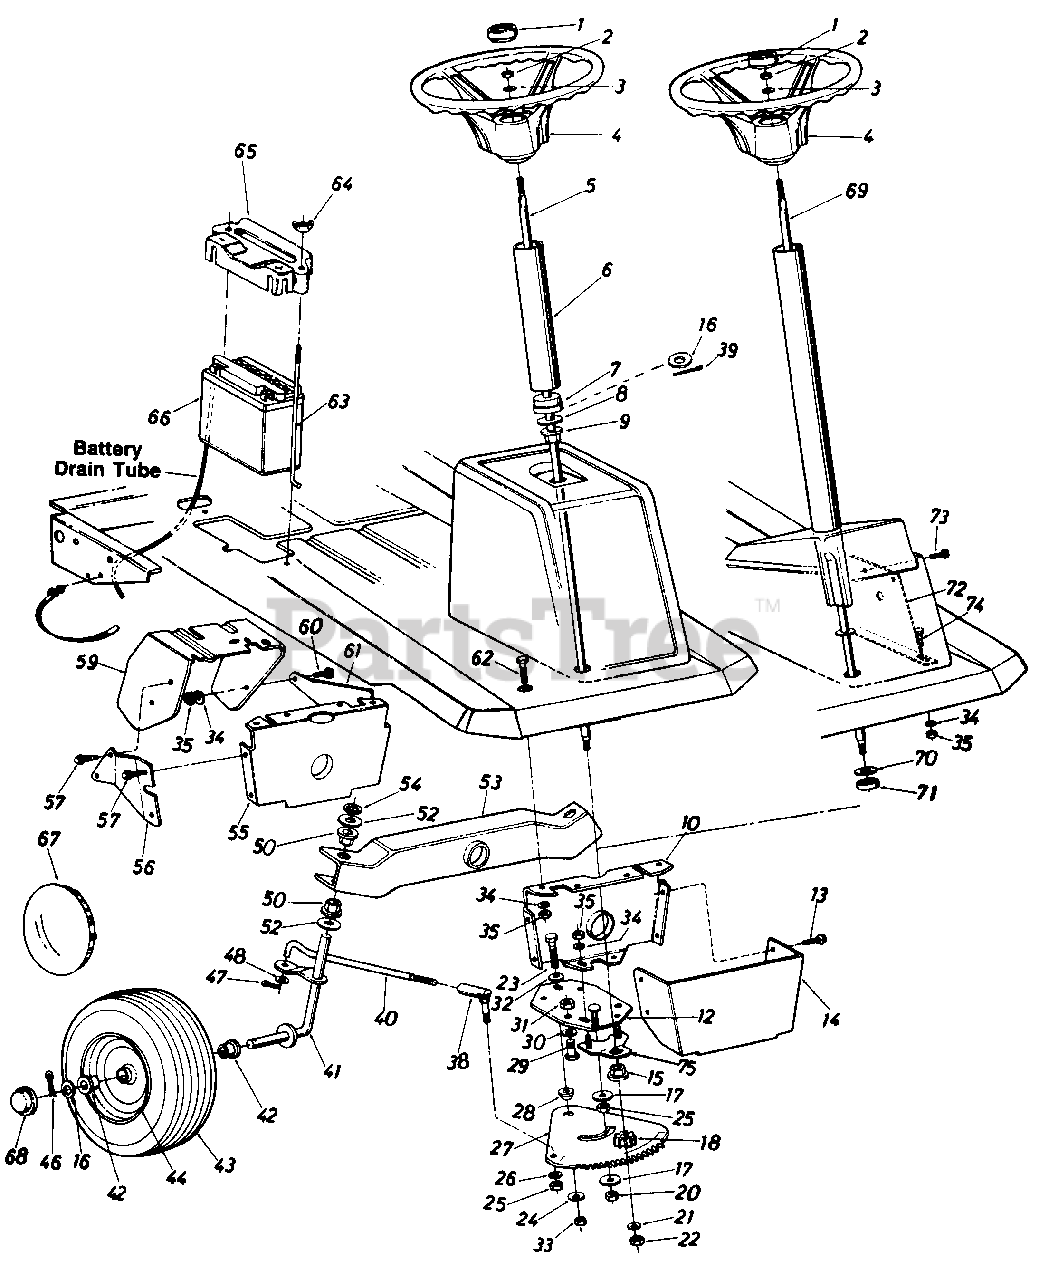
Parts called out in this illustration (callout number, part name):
1	Steering Wheel Cap
2	Hex L-Nut 5/16-24 Thd.
3	Bell-Wash. .345" I.D. x .88" O.D.
4	Steering Wheel Ass'y.
5	Steering Shaft
8	Fl-Wash. .635" I.D. x 1.24" O.D.
9	Hex Flange Bearing
10	Pivot Bar Bracket
12	Steering Gear Support Brkt.
13	Hex Wash. Hd. AB-Tap Scr. 1/4 x .62" Lg.
16	Fl-Wash. .640" I.D. x 1.5" O.D.
17	Fl-Washer 3/8" I.D. x 1.37" O.D.
18	Steering Pinion Gear
20	Hex L-Nut 3/8-24
21	Fl-Wash. .34" I.D. x .68" O.D.
22	Hex L-Nut 5/16-24 Thd.
23	Hex Bolt 3/8-24 x 1.5" Lg. (Grade 5)
24	Fl-Wash. .385" I.D. x 1.38"
25	Hex Nut 3/8-24 Thd.
26	L-Wash. 3/8" I.D.
27	Steering Gear Segment
28	Shoulder Spacer .622" Dia. x .218
29	Hex Bolt (Nylon) 1/2-13 x 75"
30	Fl-Wash. .530" I.D. x 930"
31	Hex Nut 1/2-13 Thd.
32	Bell-Wash. .385" I.D. x .88"
33	Hex Nut 3/8-24 Thd.
34	L-Wash. 5/16" I.D.
35	Hex Nut 5/16-18 Thd.
38	Ball Joint Ass'y. 3/8-24 Thd.
39	Cotter Pin 1/8" Dia. x 1.00"
40	Steering Tie Rod
41	Front Axle Ass'y.-R.H.
42	Flange Bearing
43	Front Wheel Ass'y. Comp.
44	Front Wheel Rim Only
46	Cotter Pin 1/8" Dia. x 1.25"
47	Cotter Pin 1/8" Dia. x 1.00"
48	Fl-Wash. .385" I.D. x .87"
50	Hex Flange Bearing
52	Fl-Wash. .635" I.D. x 1.12"
53	Pivot Bar Ass'y.
54	Speed Nut 5/8" I.D.
55	Pivot Bar Bracket
56	Bracket Reinforcement-R.H.
57	Hex Wash. Hd. AB-Tap Scr. 1/4 x.62" Lg.
59	Clutch-Brake Pedal Ass'y.
60	Hex Bolt 5/16-18 x .75" Lg.
63	Battery Hold Down Rod
64	Wing Nut Solid 1/4-20 Thd.
65	Battery Hold Down Cover
66	12V Battery
67	Chrome Hub Cap
68	Plastic Hub Cap
69	Steering Shaft Ass'y.
70	Fl-Wash. .635" I.D. x 1.24" O.D.
71	Spacer (Plastic)
74	Hex Bolt 5/16-18 x 2.00" Lg.
75	Steering Gear Adjuster Ass'y.
